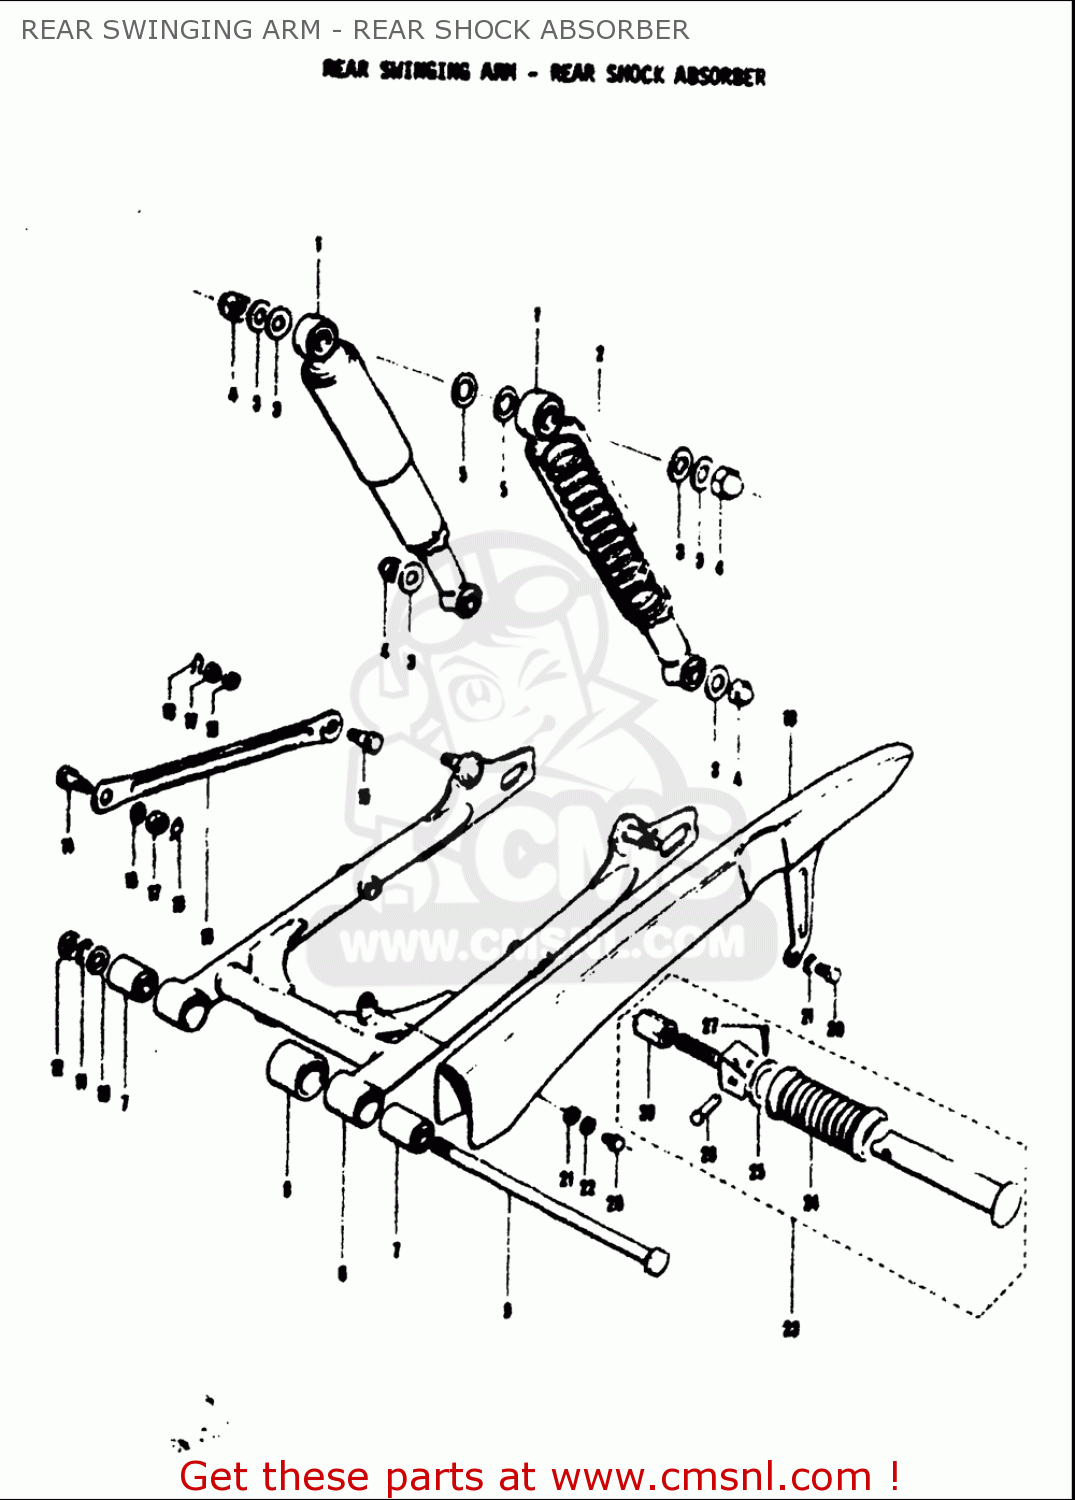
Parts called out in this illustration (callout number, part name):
3	WASHER (10.5X24X2.3)
4	NUT
5	WASHER
7	BUSHING(10X23X35)
10	WASHER
11	WASHER,LOCK
16	WASHER,LOCK
17	NUT
18	RETAINER,SNAP
21	WASHER
22	WASHER,LOCK
24	RUBBER,PILLION FOOTREST
25	WASHER(19.5X32X2)
26	PIN
28	NUT
